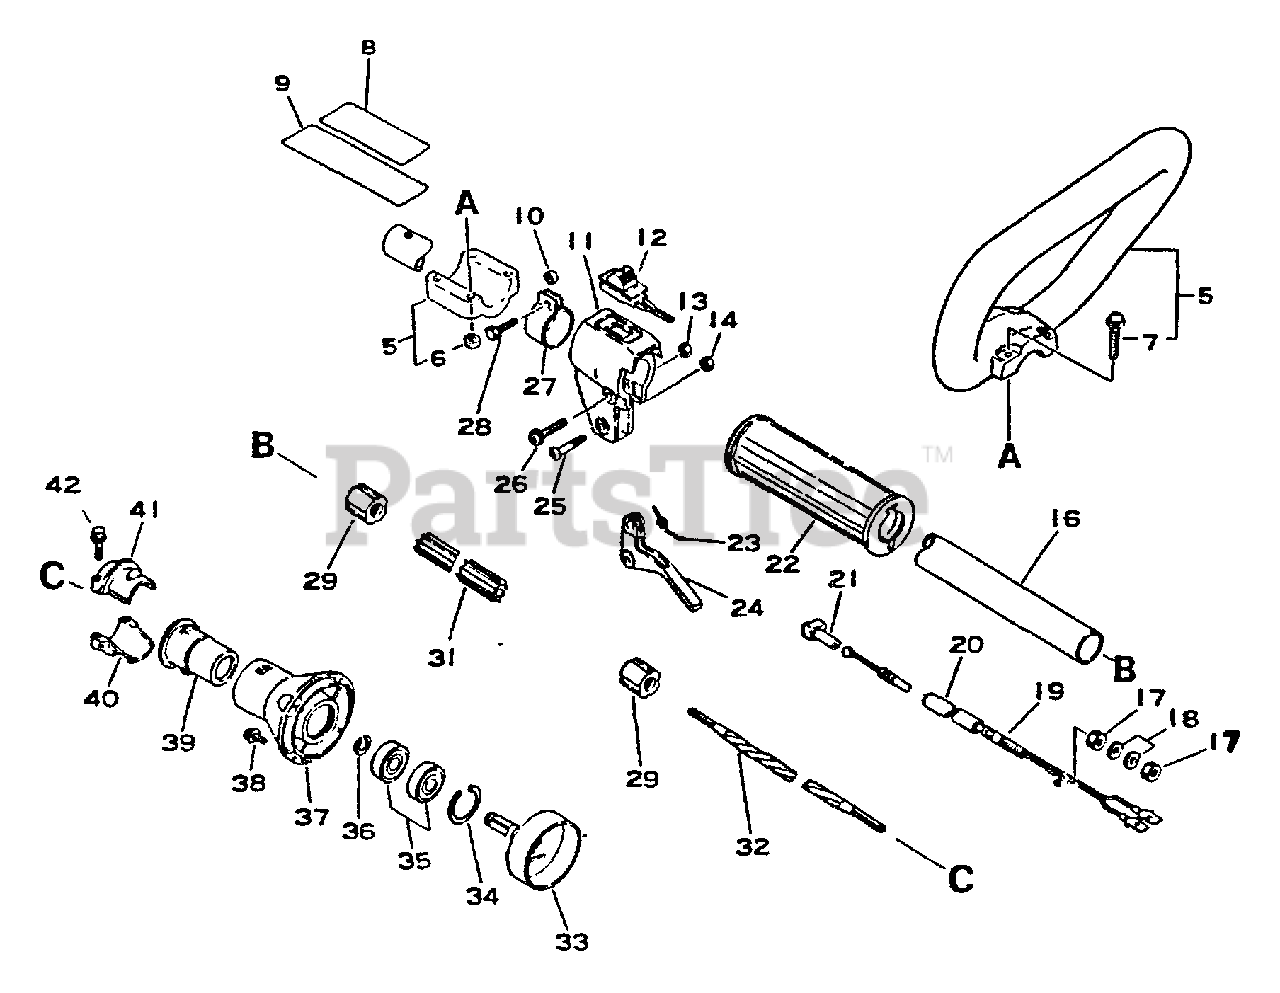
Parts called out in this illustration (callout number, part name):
5	LOOP HANDLE ASSY
6	NUT M5
7	SCREW 5×35
10	SPACER, GUARD
11	BRACKET, THROTTLE CONTROL
12	IGNITION SWITCH ASSY
13	NUT M5
14	LOCKNUT - 5
16	PIPE, MAIN
18	WASHER 6.5×11.5×0.8
19	CABLE, THROTTLE
21	GUIDE, CABLE
22	GRIP, HANDLE
23	SPRING, THROTTLE
24	TRIGGER, THROTTLE
26	SCREW 5×30
28	BOLT 5×18
31	LINER, FLEXIBLE 21.6×1420
32	DRIVESHAFT - FLEXIBLE L= 1522
33	DRUM, CLUTCH
34	RING, SNAP 28
35	BEARING, BALL 6001
36	RING, RETAINING - 12
37	CASE, CLUTCH
38	SCREW 5×16
41	HOLDER, MAIN PIPE - UPPER
42	BOLT - 5×25
